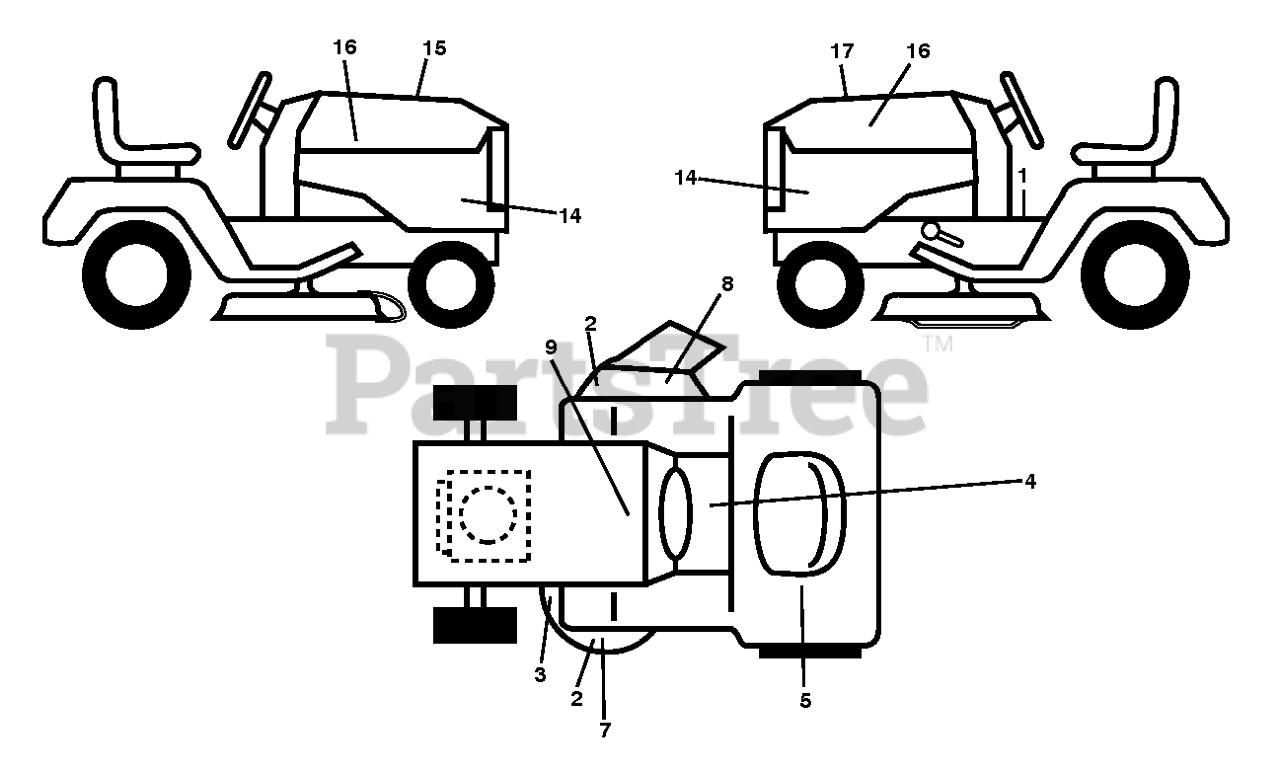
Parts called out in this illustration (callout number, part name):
1	DECAL.FENDER.WARNING.ENGLISH
2	DECAL.DECK.CLEARCUT.NOSTEP
3	DECAL.MOWER.SCH.48/54.PREM
4	DECAL, WARNING SPARK ARRESTOR
5	DECAL.RESERVEFUELSELCTR.ENG
7	DECAL.HV.REINFORCED.DECKS.2012
8	DECAL.TRACT/ZTR.DECKWARN.HUSQ
9	DECAL BTRY SYMBOLS
14	DECAL.SDPNL.HUGT2.GT48DXLS.R/L
15	DECAL.WARNING.CUST.RESP.E85.
16	DECAL.BADGE.170MM.TEXTLOGO.
17	DECAL.RPL.KW.FR.TGB.48F.K66AL
